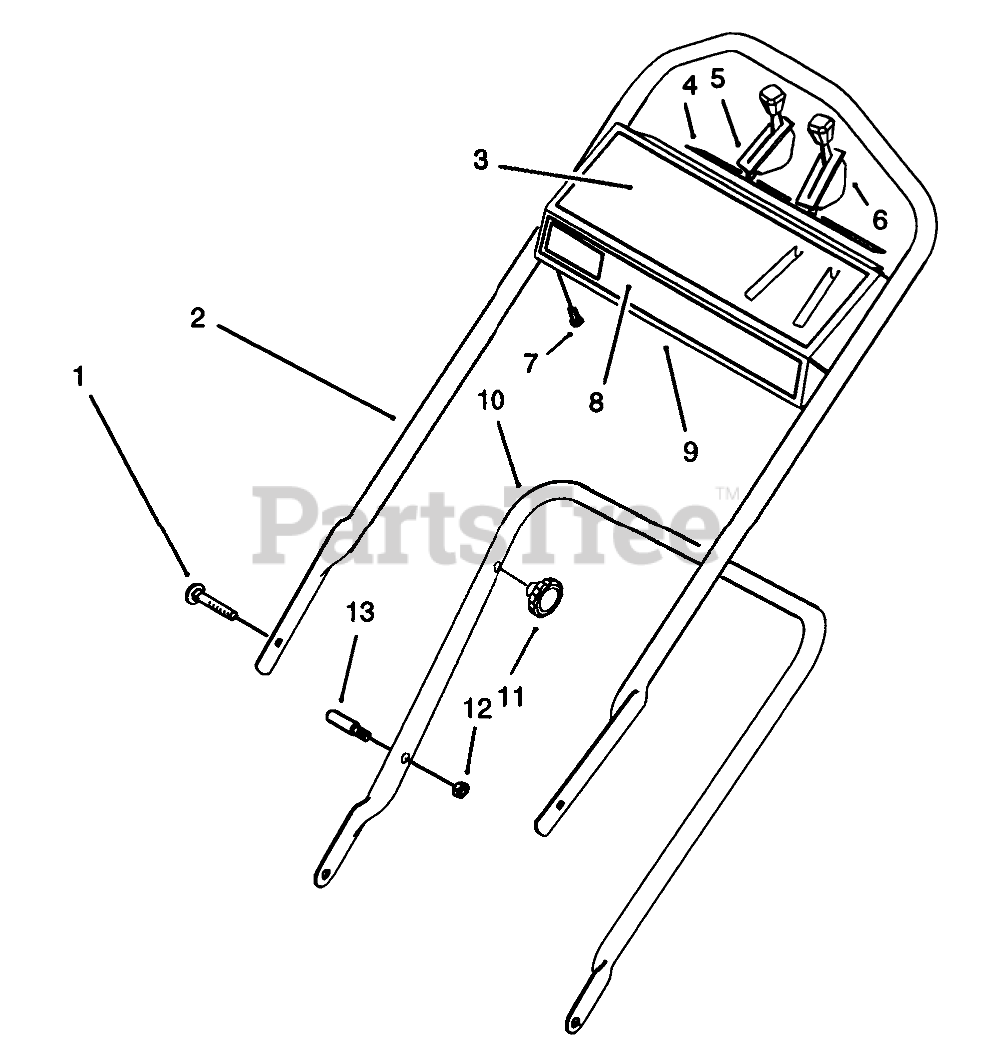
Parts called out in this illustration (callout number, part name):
1	5/16-18 X 2 HNDLE SCREW
2	UPPER HANDLE, PVC DIP
3	DECAL - INSTR (INT'L)
4	DECAL - PANEL, REAR
5	Control-Traction (Bend Type #3) Sheath Lg. 46")(Wire Lg. 2")
6	THROTTLE CONTROL - R&S
7	SCREW-HWHTF
8	DECAL - TORO PANEL
9	Panel-Control (Incl. Ref. #4 & 28)
10	LOWER HANDLE ASM
12	NUT-LOCK, NI
13	HANDLE PIN
